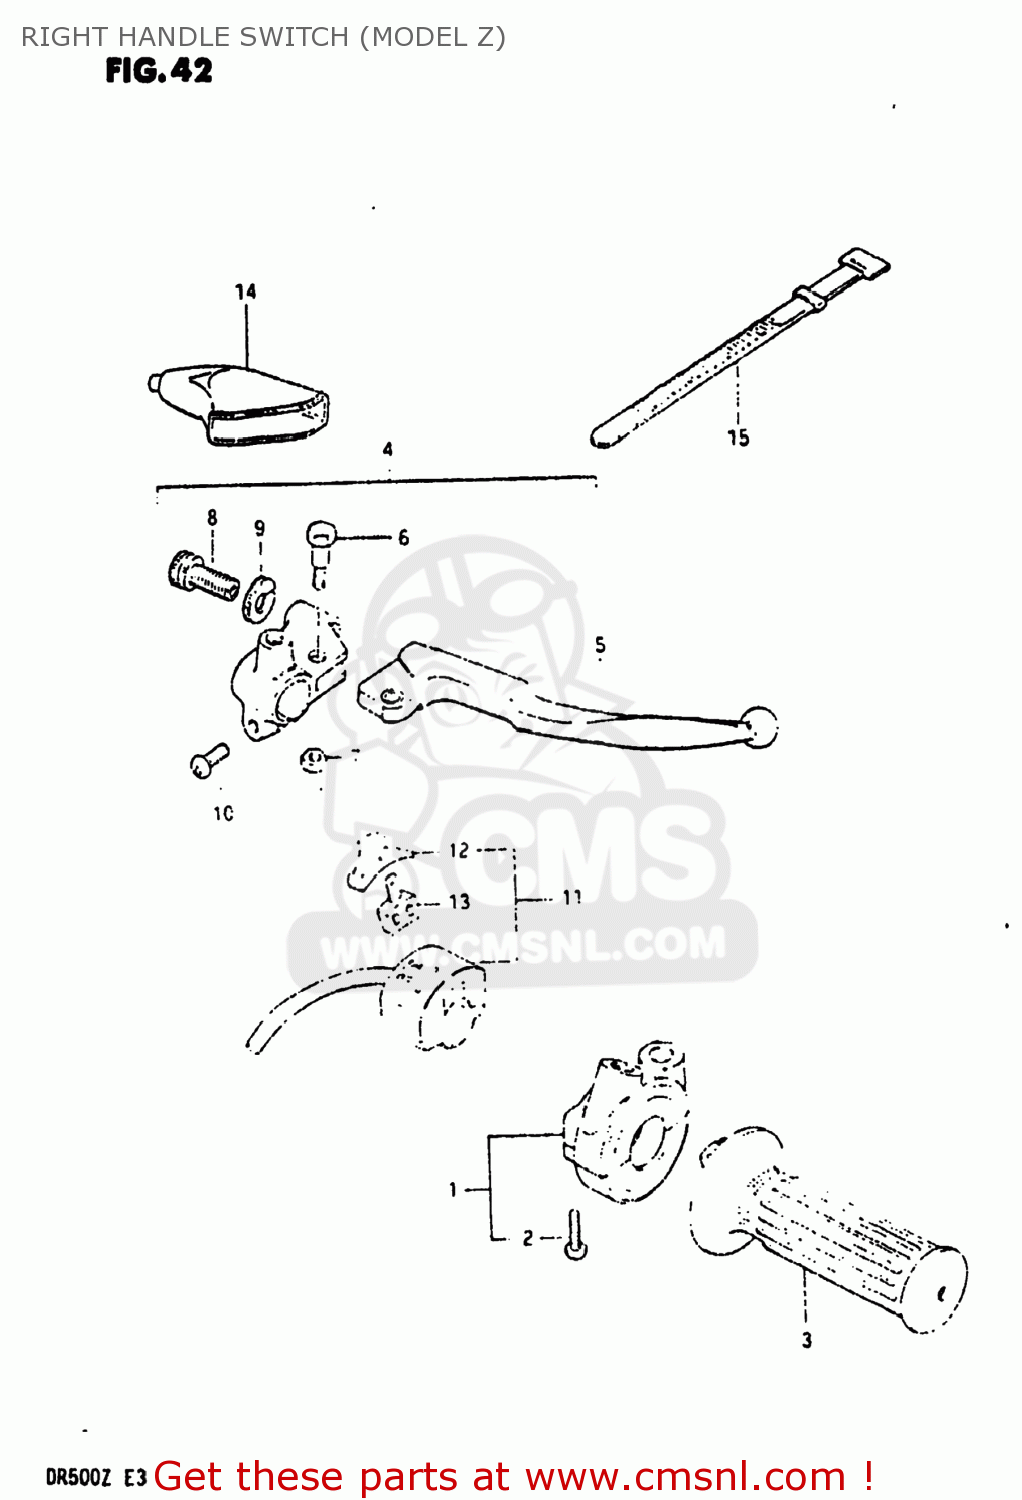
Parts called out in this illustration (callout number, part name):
1	CASE ASSY,THROTTLE
2	SCREW 5X20
3	GRIP,THROTTLE
4	LEVER ASSEMBLY,BRAKE
5	LEVER,BRAKE
6	BOLT,LEVER
7	NUT 6MM
8	ADJUSTER,CABLE
9	NUT,CABLE ADJUSTER
10	SCREW
11	SWITCH ASSEMBLY,LIGHTING
12	KNOB,LIGHTING & DIMMER
13	BLOCK,LIGHTING/DIMMER
14	COVER,CLUTCH LEVER
15	CLAMP(L:120)
